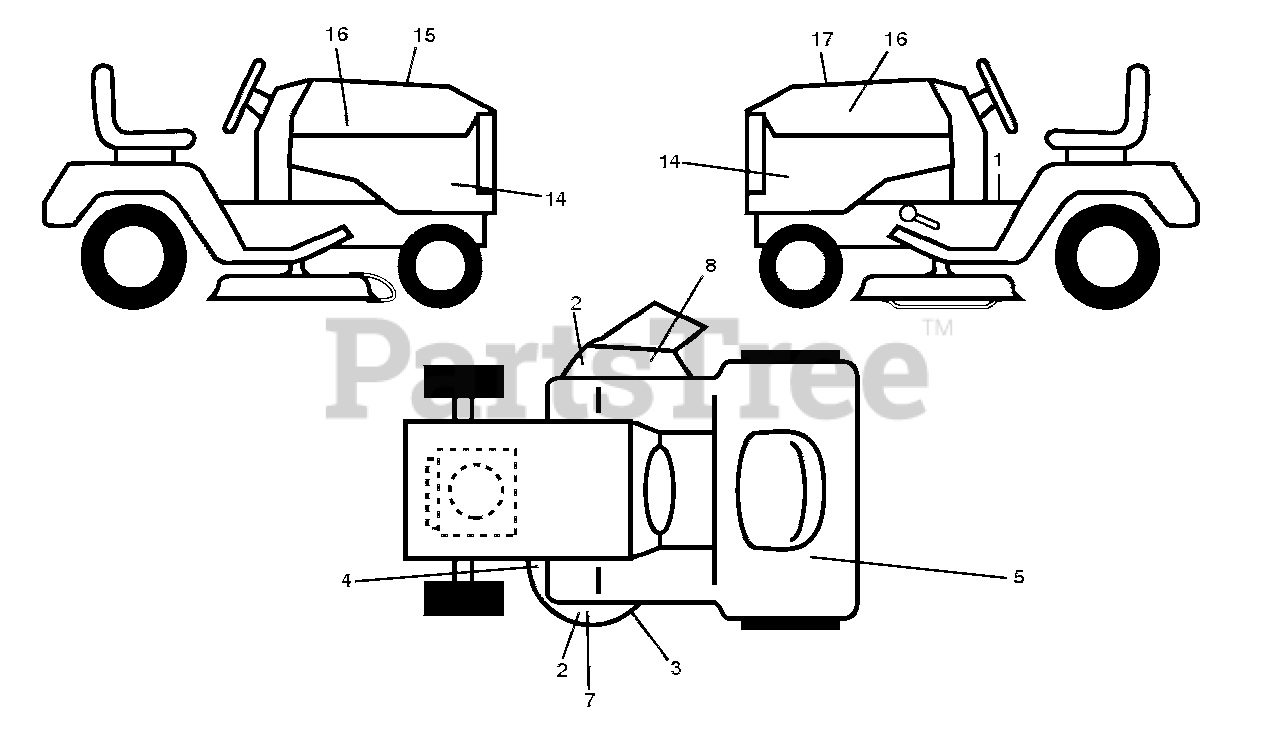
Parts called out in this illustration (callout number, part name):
1	DECAL.FENDER.WARNING.ENGLISH
2	DECAL.DECK.CLEARCUT.NOSTEP
3	DECAL.MOWER.SCH.48/54.PREM
4	Deck Decal, WA
5	DECAL.RESERVEFUELSELCTR.ENG
7	Deck Decal, 48"
8	DECAL.TRACT/ZTR.DECKWARN.HUSQ
14	Tractor Side Panel Decal
15	DECAL.WARNING.CUST.RESP.E85.
16	DECAL.BADGE.170MM.TEXTLOGO.
17	Decal, Replacement Kawasaki FR TGB 48F K66AL
